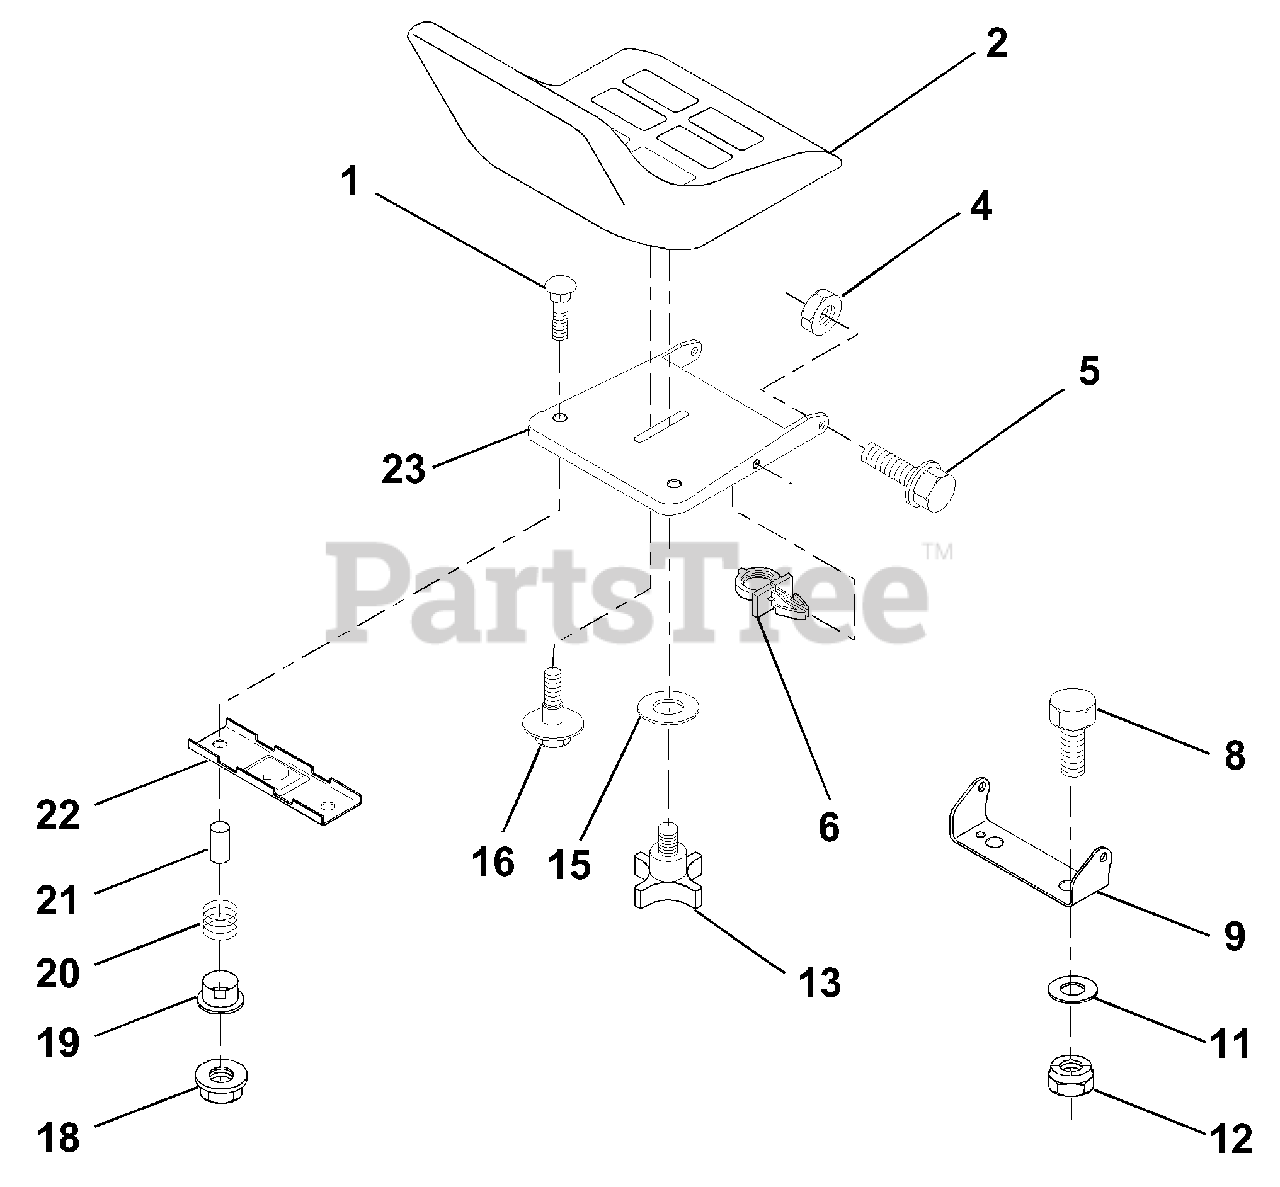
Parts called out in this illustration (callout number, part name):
1	Bolt, Carriage 1/4-20 x 1-3/8
2	Seat
4	Nut, Hex, Lock w/wsh 5/16-18
5	Bolt, Shoulder 5/16-18 UNC
6	Clip, Insulated
8	Bolt, Hex, Fin. 3/8-16 UNC x 1
9	Bracket, Pivot, Seat
11	Washer 12/32 x 2 x 10 Gauge
12	Nut, Hex, Lock Hex w/wsh 3/8-16
13	Knob, Seat
15	Washer 17/32 x 1-3/16 x 12 Gauge
16	Bolt, Shoulder
18	Nut, Hex, Large, Flange Lock
19	Bushing, Snap
20	Spring, Compression
21	Spacer, Split, Large .28 Id. x .96
22	Bracket, Switch Mounting
23	Pan, Seat
